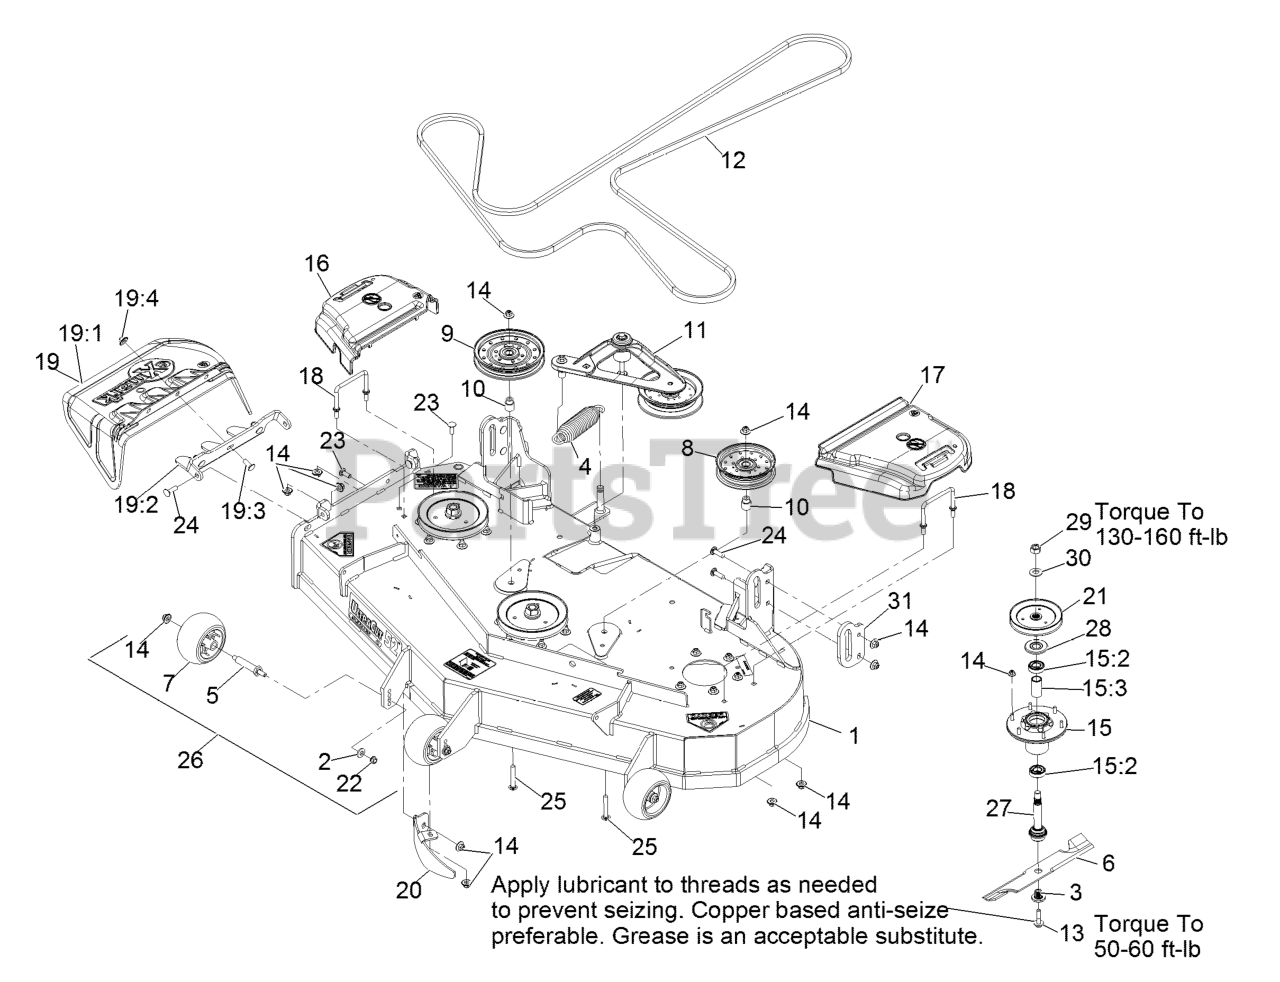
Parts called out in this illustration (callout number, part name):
1	ASM, DECK W/DECALS 524
2	WASHER-BELLEVILLE
3	BUSHING,SPLINED
4	SPRING-EXTENSION
7	ROLLER-SCALP, ANTI
10	BUSHING-IDLER
11	DECK IDLER ASM
12	BELT,V-B X 186.00"
13	SCREW,SEMS 1/2-20 X 2.19
14	Nut-Nyloc 3/8-16 Flg
15	ASM-CUTTER HSG WITH BEARINGS
15:2	BEARING-BALL
15:3	SPACER-BEARING
16	COVER-BELT, RH
17	COVER-BELT, LH
18	WIREFORM-COVER
19	ASM,DISCHARGE CHUTE
19:1	CHUTE,DISCHARGE
19:2	BRACKET,DISCHARGE CHUTE
19:3	SCREW-CARR
19:4	Nut-Nyloc 3/8-16 Flg
20	BAFFLE-DOGLEG, LZE-PNS-52
21	SHEAVE,BLADE DRIVE 6.50
22	NUT-HHF, WHIZ
23	SCREW-CARR
24	Bolt-Carriage 3/8-16 X 1 1/4
25	SCREW-CARR
27	ASM-SPINDLE AND SEAL
28	GUARD,BEARING TOP .989
29	NUT-HEX
31	PLATE-REINF, PUSH TOWER
